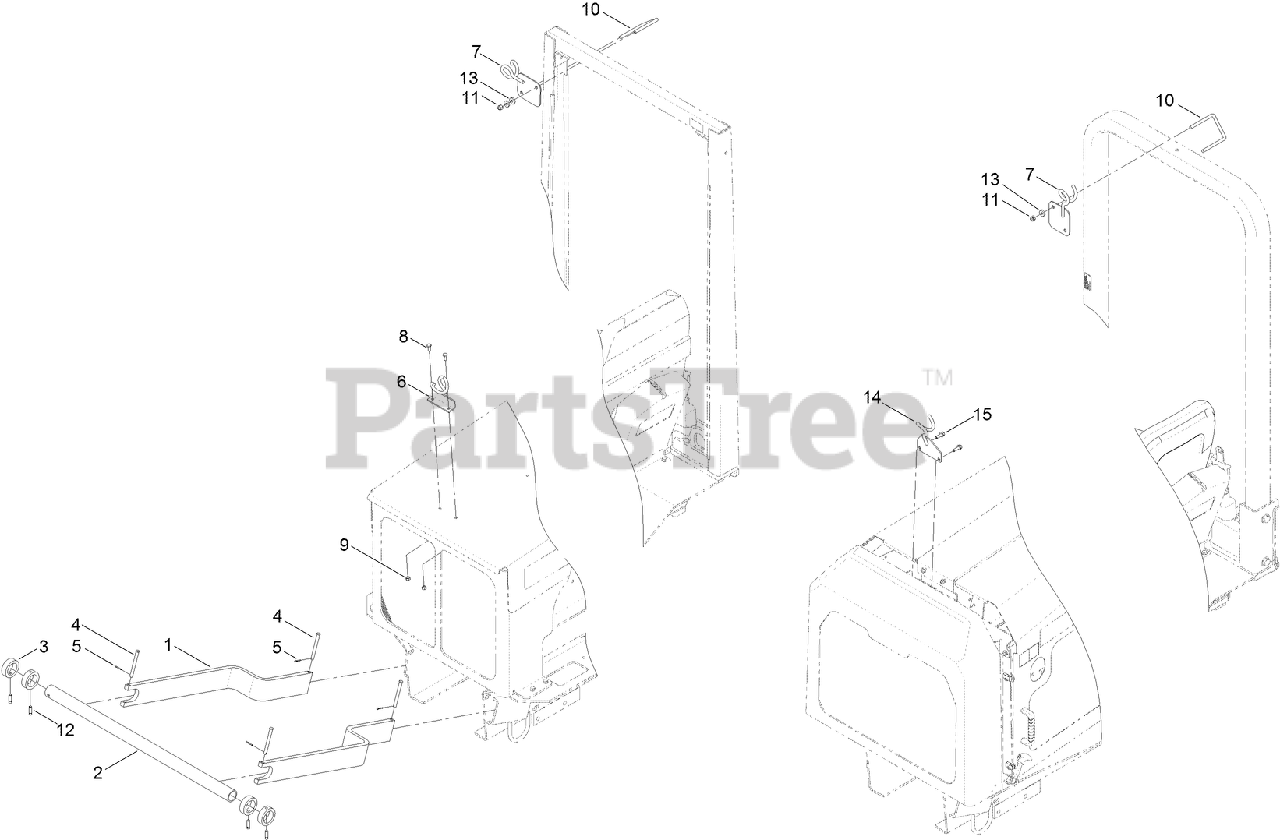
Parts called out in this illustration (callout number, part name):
1	ARM-REEL CARRIER
2	PIPE-CARRIER
3	COLLAR-STOP
4	PIN-CLEVIS
5	PIN-COTTER
6	GUIDE-CABLE
7	GUIDE-CABLE
8	SCREW-HHF
9	NUT-LOCK, CONE
10	U-BOLT (4 INCH)
11	NUT-LOCK, NI
12	SCREW-SET, SQH
13	WASHER
14	PLATE-GUIDE
15	SCREW-HHF
